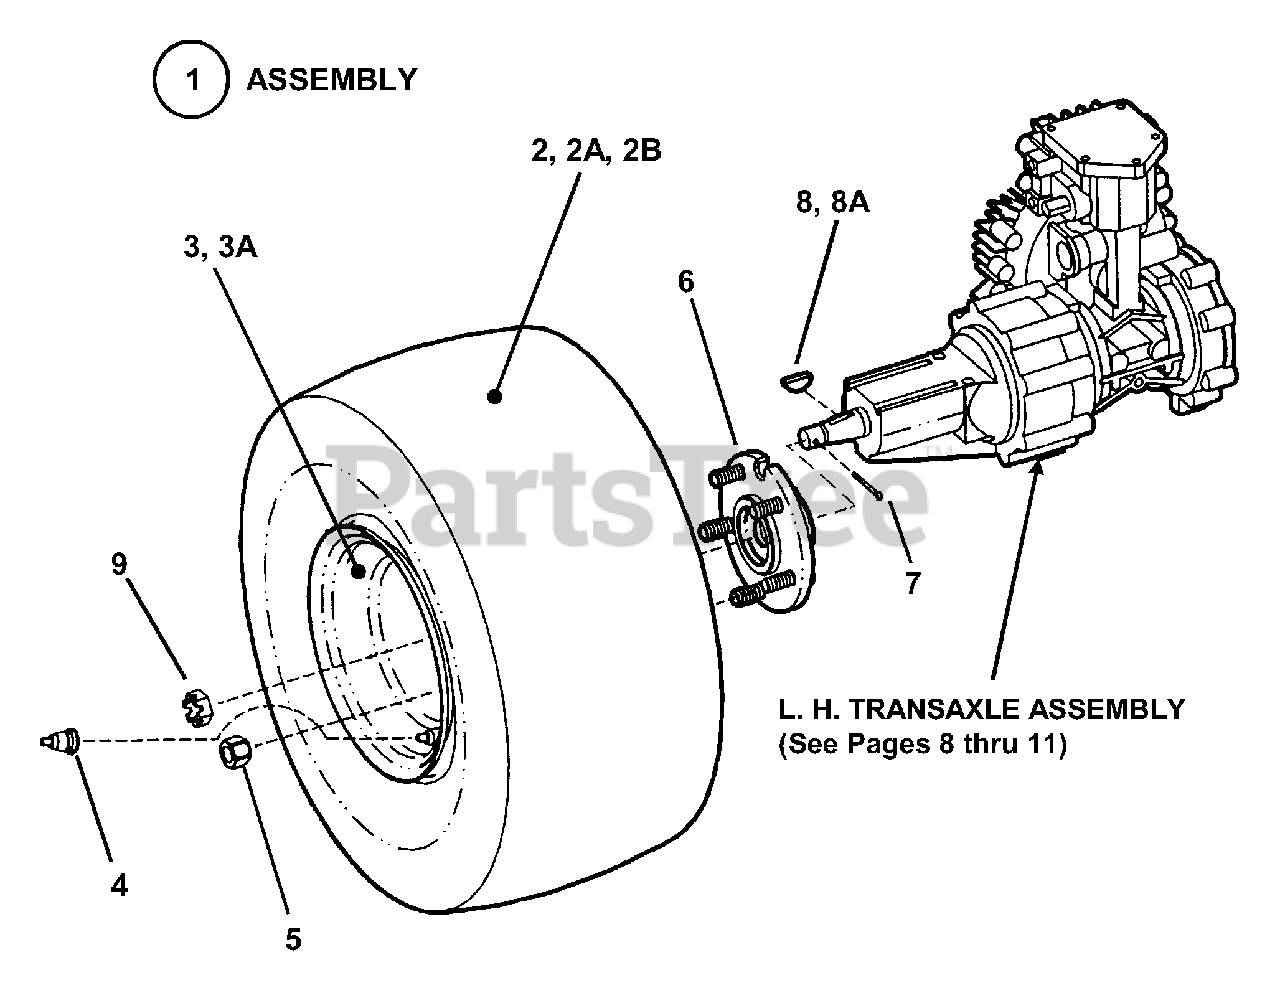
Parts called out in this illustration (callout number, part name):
1	ASSEMBLY, Rear Tire & Rim
2	TIRE, 23 x 10.5 - 12 NHS
2A	TIRE, 21 x 11 - 8 AG (Model MZM2200KH Only)
2B	TIRE, 23 x 10.5 - 12 "Turf Mate"
3	RIM, 12" Diameter x 7.00"
3A	RIM, 8" Diameter x 6-3/8 (Model MZM2200KH Only)
4	VALVE, Air
5	NUT, 1/2-20 Lug
6	ASSEMBLY, Wheel Hub
7	PIN, 9/64 x 1-1/2" Cotter
8	KEY, #808 Woodruff
8A	KEY, #806 Woodruff (Model ZMT2500KH, ZM2501KH, ZM2502KH)
9	NUT, 3/4-20 Slotted Hex
